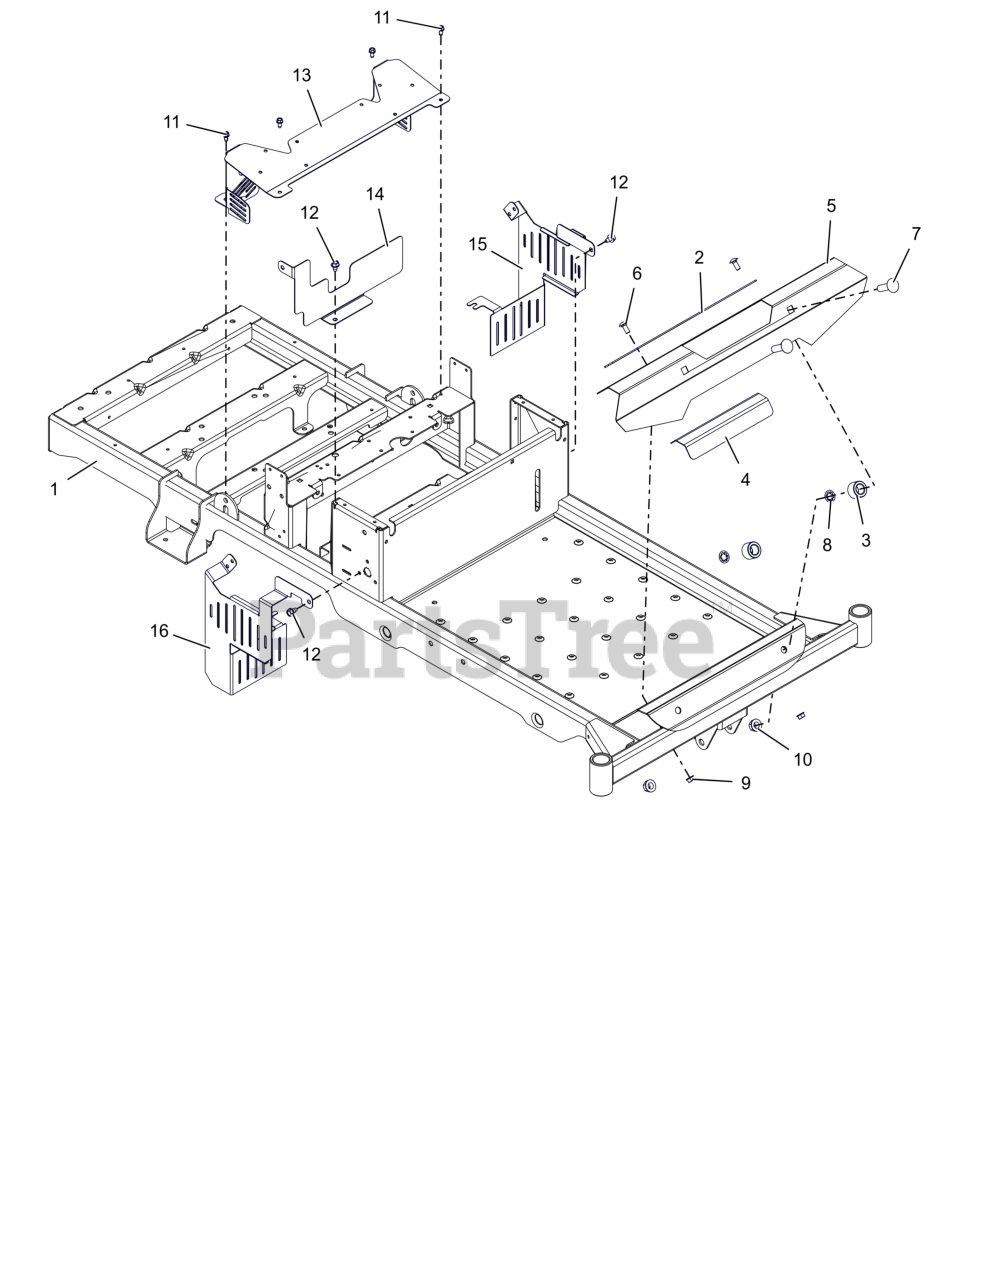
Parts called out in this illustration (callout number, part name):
1	KIT- EDGE FRAME W/DECALS
2	GRIP, ADHESIVE (1" X 16" BLK)
3	TUBE, UPPER CONTROL PIVOT
4	GRIP, STEP
5	FOOTREST, (ORANGE)
6	BLT, RHSSN.31-18X.750 G5 ZCC
7	BLT,RHSN .50-13X1.75 G5 ZCC
8	NUT-PUSH, .50
9	NUT,LK-CTR-FLG .31-18 GF ZCC
10	NUT-LK-CTR-FLG .500-13 GG ZCC
11	SCR-TAP .25-20X.50 HWH ZCC
12	SCR,TAP .312-18X.50 HWH TR ZCC
13	PLATE, FAN GUARD,CE
14	MUFFLER, LONCIN 635CC
15	SHIELD, LOWER TRANSAXLE LH CE
16	SHIELD, LOWER TRANSAXLE RH CE
